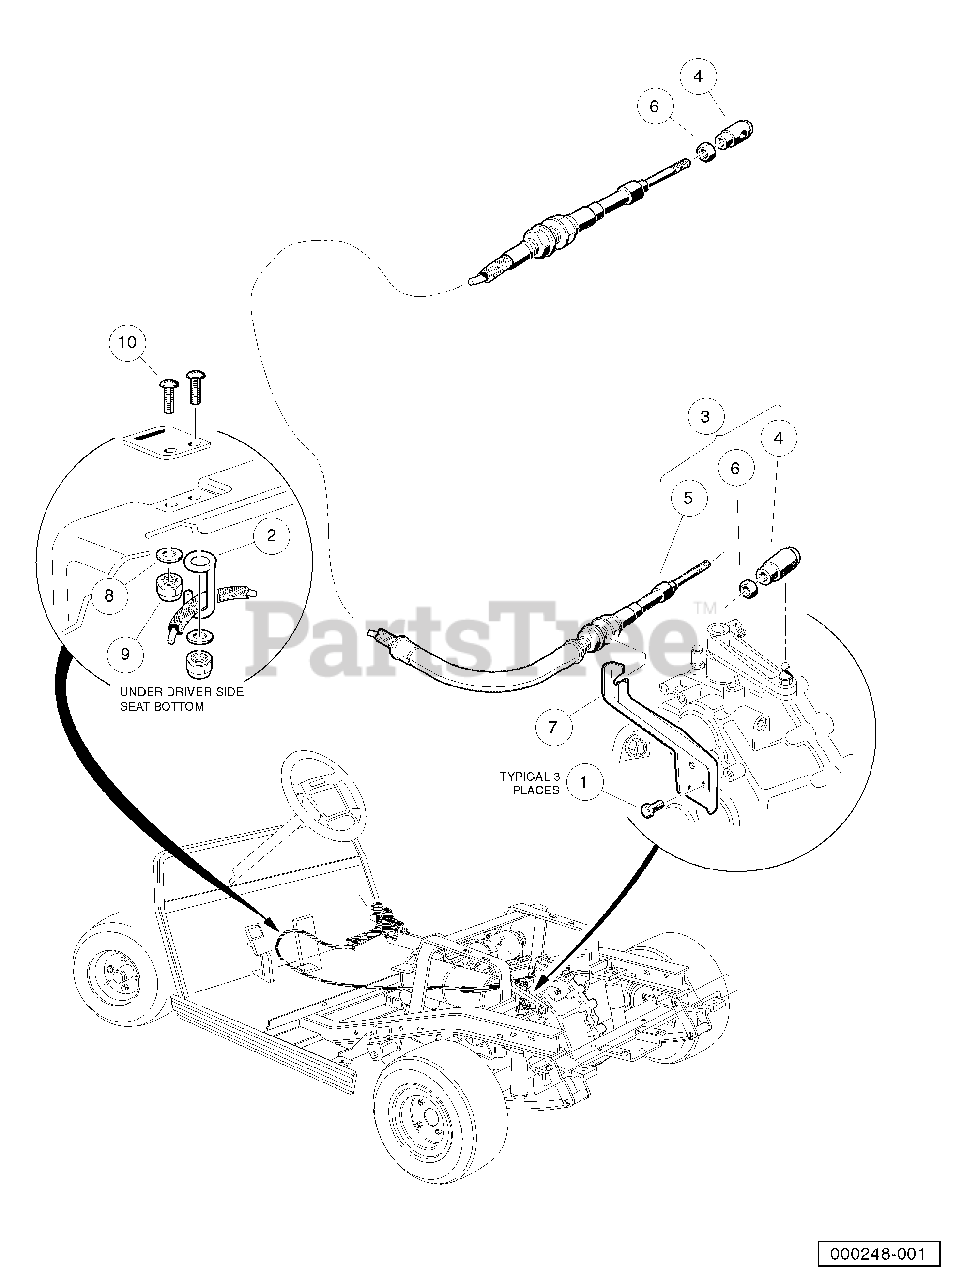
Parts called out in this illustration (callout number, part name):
1	Screw, 1/4 X 0.625 Hex-Head
2	Cable Retainer
3	FNR Shifter Cable
4	Joint, #10-32 Ball
5	Cable, Forward/Reverse Shifter
6	Nut, #10-32 Hex
7	Bracket, Shifter
8	Washer, 1/4 Type A Narrow Flat
9	Locknut, 1/4-20 Nylon Insert
10	Screw, 1/4-20 X 1.0 Truss-Head Machine
